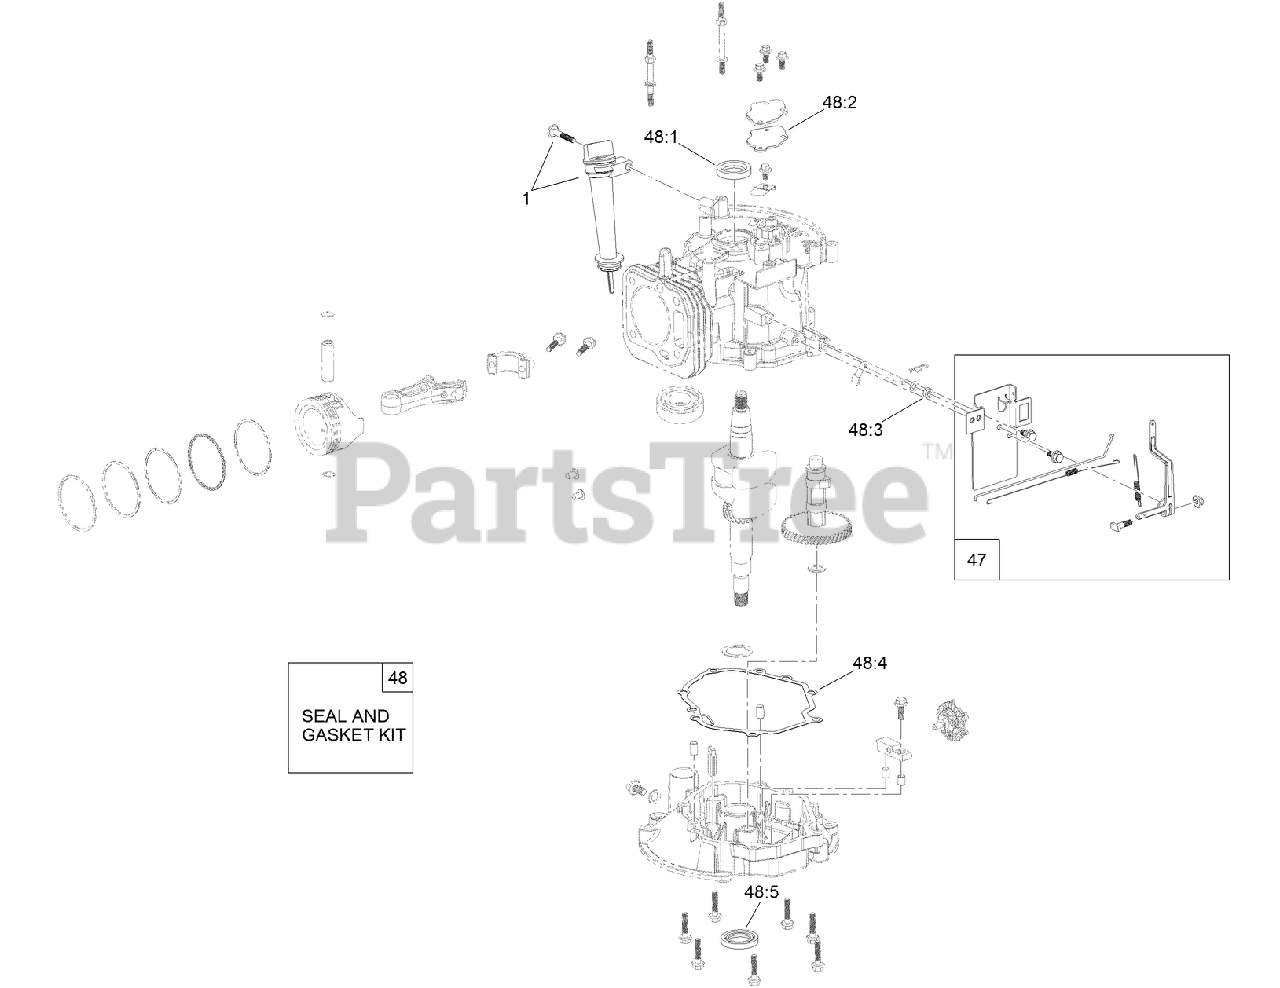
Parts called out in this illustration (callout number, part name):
1	DIPSTICK AND FILL TUBE KIT
47	GOVERNOR ARM KIT
48	SEAL AND GASKET KIT
48:1	SEAL-OIL
48:2	GASKET-BREATHER
48:3	SEAL-OIL
48:4	GASKET-COVER, CASE
48:5	SEAL-OIL
